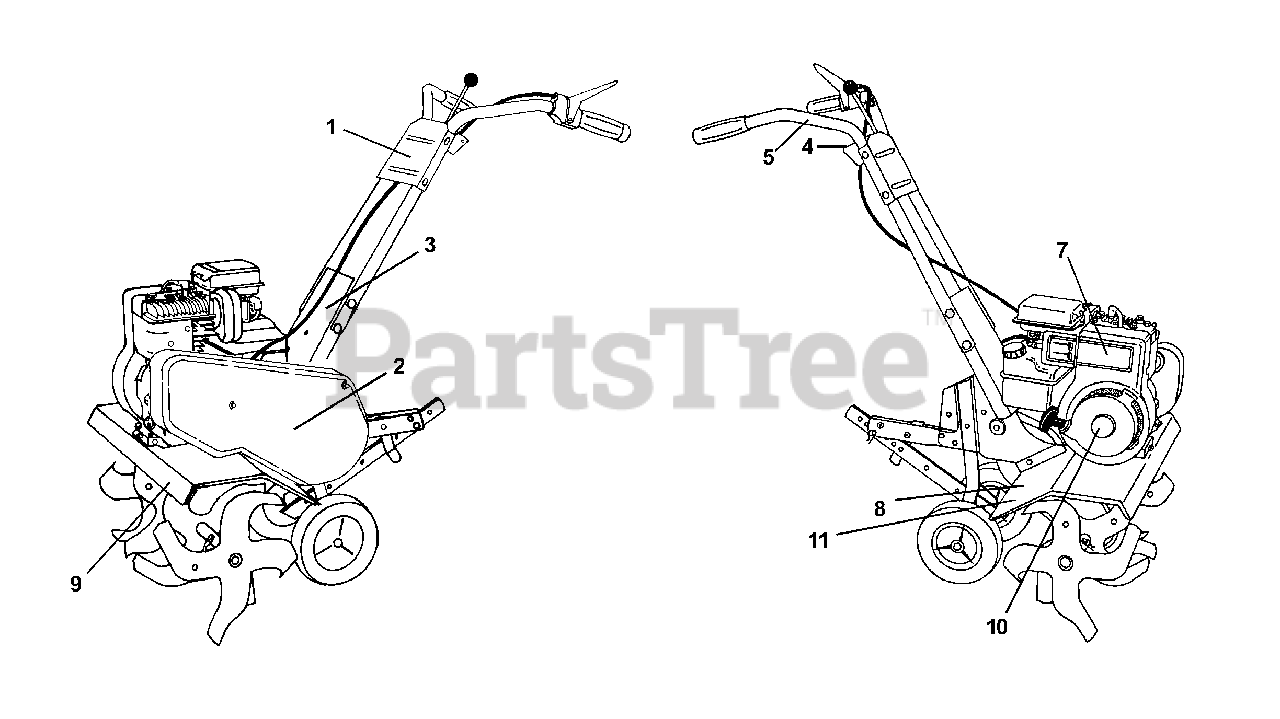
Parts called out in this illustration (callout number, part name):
1	Decal, Logo
2	Decal, Logo
3	Decal, HP, Reverse
4	Decal, Reverse, Tine Control
5	Decal, Hand Placement
7	Decal, Briggs & Stratton
8	Decal, Warning, Rotating Tines
9	Decal, Hvy Duty
10	Decal, 5 HP
11	Decal, Tine Shield Wrng. Dom
